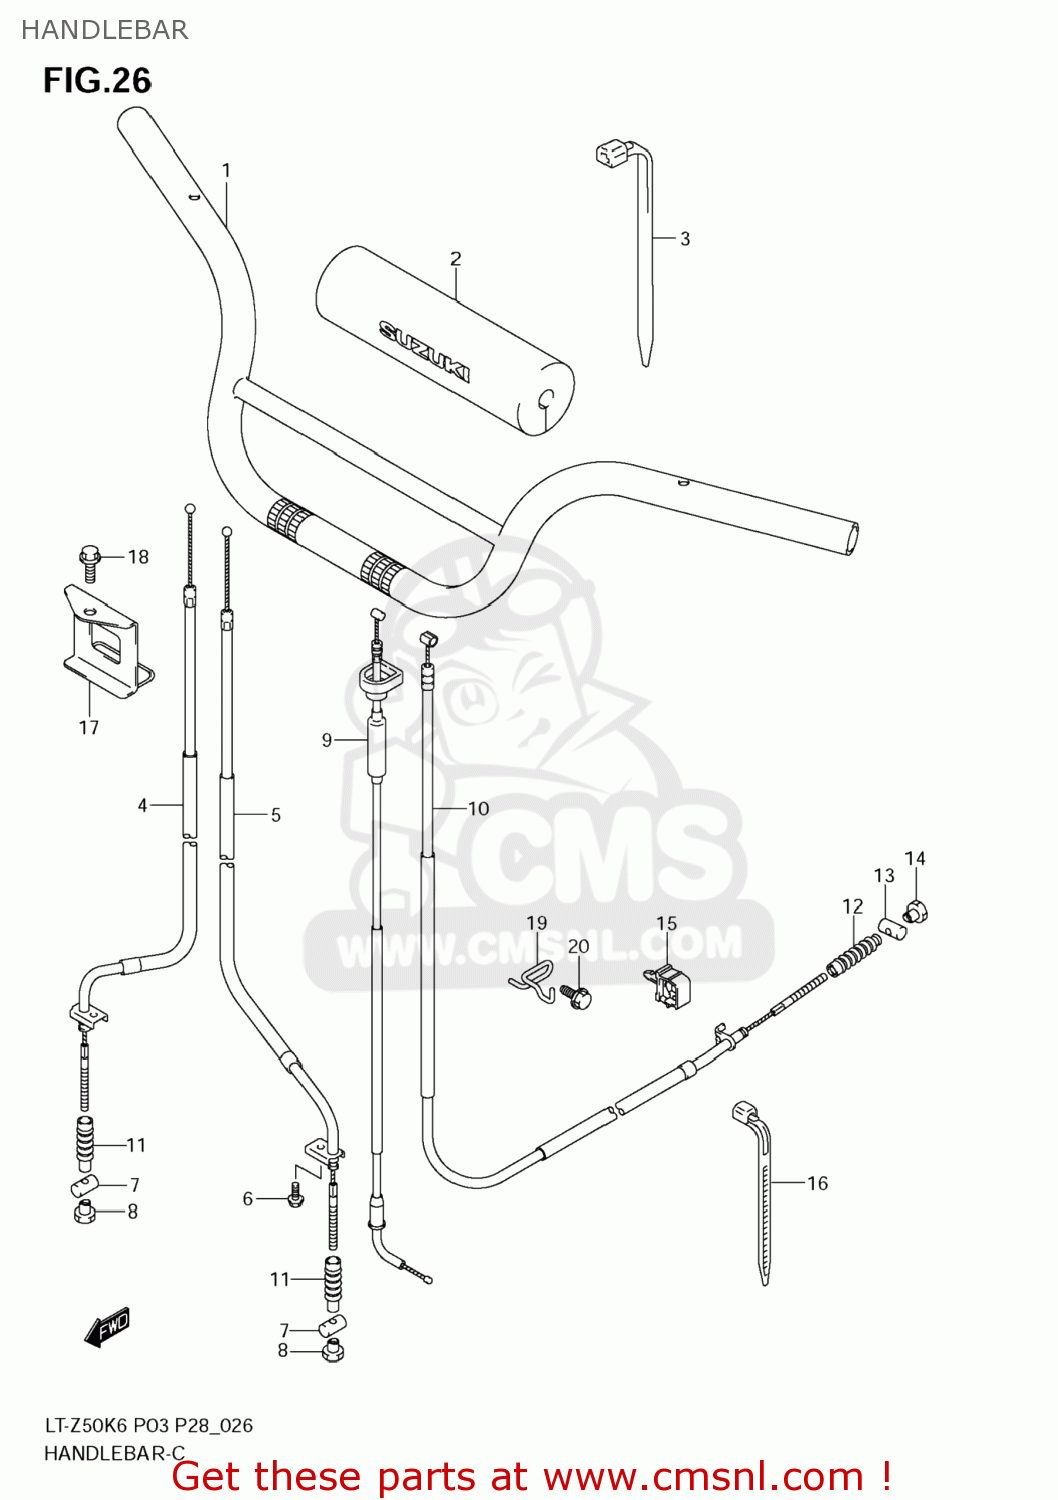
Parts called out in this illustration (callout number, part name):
1	HANDLEBAR(SILVER)
2	PAD,CROSS BAR
3	CLAMP(L:187)
4	CABLE,FR BRAKE,R
5	CABLE,FR BRAKE,L
6	BOLT(6X10)
7	PIN,10X19
8	NUT
9	CABLE ASSY,THROTTLE
10	CABLE,RR BRAKE
11	BOOT,BRAKE CABLE
12	BOOT,FR BRAKE CABLE
13	PIN,10X19
14	NUT
15	CLAMP
16	CLAMP(L:125)
17	GUIDE,FR BRAKE CABLE
18	BOLT
19	GUIDE,RR BRAKE CABLE
20	BOLT(6X12)
